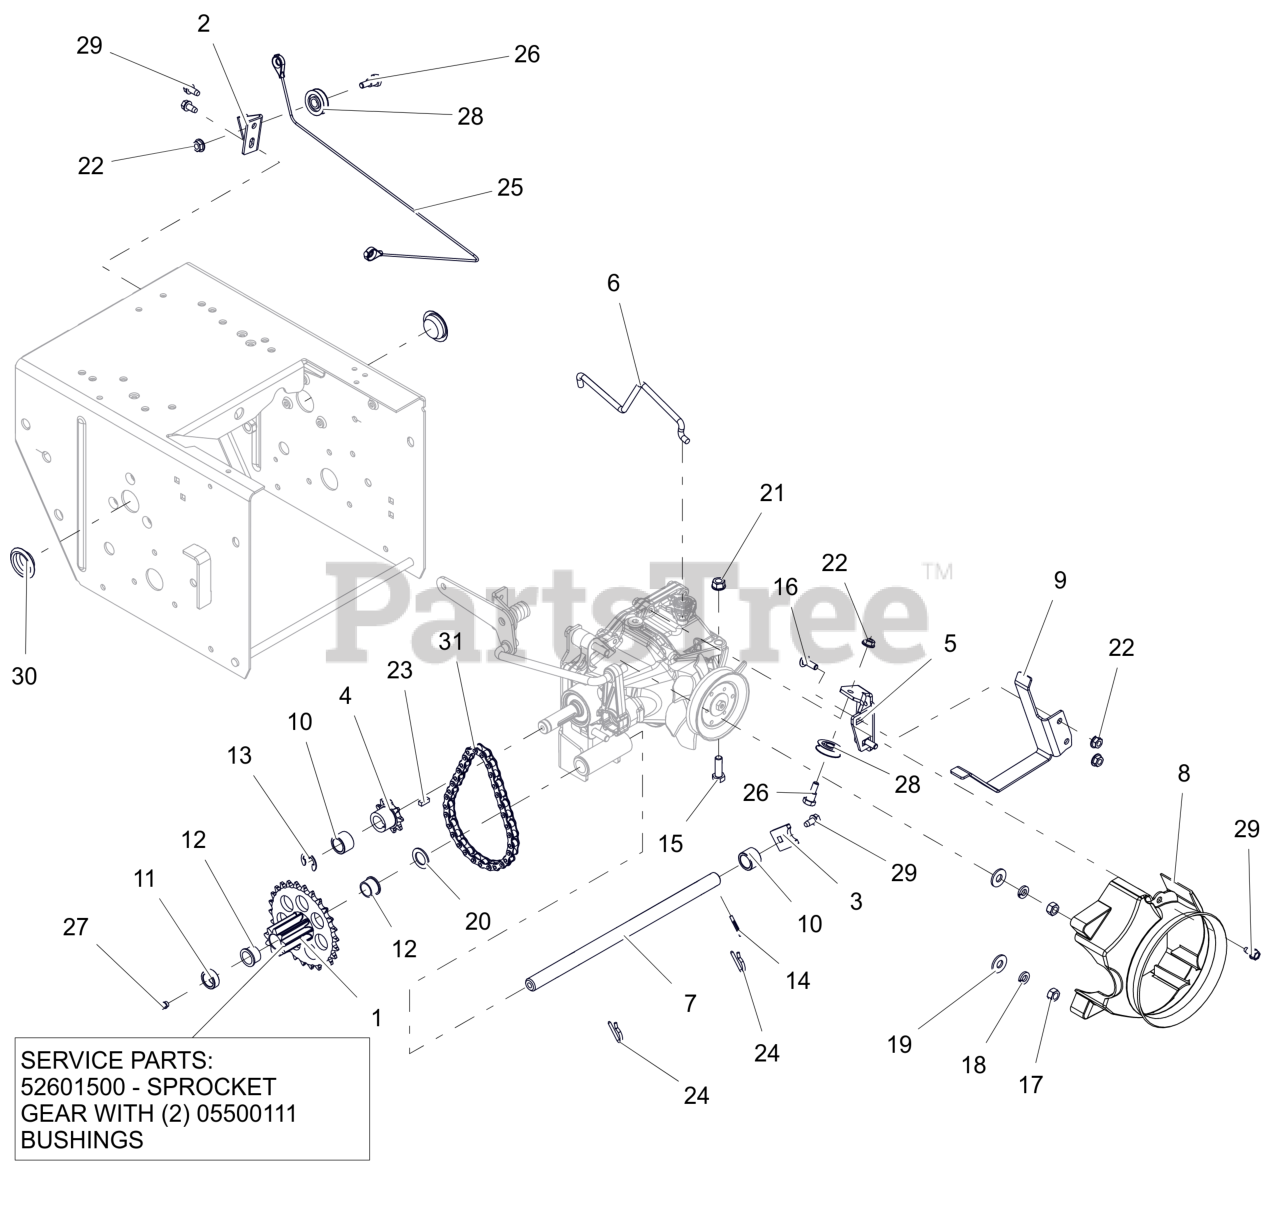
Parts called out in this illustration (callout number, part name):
1	PINION & SPROCKET
1	PINION & SPROCKET W/BUSHINGS
2	BRACKET, CABLE PULLEY
3	TAB, ANTI ROTATION
4	SPROCKET, PINION 9T W/KEY
5	BRACKET, CLUTCH CABLE
6	ROD, HYDRO BYPASS
7	SHAFT, PINION - HARDENED
8	SHROUD, HYDROGEAR RT-310
9	FINGER, BELT - FLAT
10	SPACER, .635X.880X.611
11	BSHG-SLV, .635X.880X.305
12	BSHG-FLG .625X.750X.500X.875
13	RG-RTNG-EXT .625X.042
14	@PIN-GRV .125X1.00 TP E ALLOY
15	BLT,HEX .31-18X1.00 G5 ZCC
16	BLT, RHSN .25-20X.750 G5 ZCC
17	NUT, HEX .312-18 ZCC
18	WSHR, LK-HVY .312X.097 ZCC
19	WSHR,FLT .375X.875X.083 ZCC
20	WSHR, FLT .630X1.005X.062 ZCC
21	NUT-LK-TOP-FLG .312-18 GF ZCC
22	NUT-LK-TOP-FLG .250-20 GF ZCC
23	KEY-SQ .187 X .50 X .187
24	PIN, SPRING CLIP
25	CABLE, TRACTION, HYDRO PRO
26	BOLT, SHLDR -.375 X .375 X .25-20
27	ZERK,FITTING .25X.125 DRIVE IN
28	PULLEY, CABLE
29	SCR-TAP .25-20X.50 HWH ZCC
30	PLUG, HOLE - 1.125"
31	CHAIN - #41, 32 PITCHES
